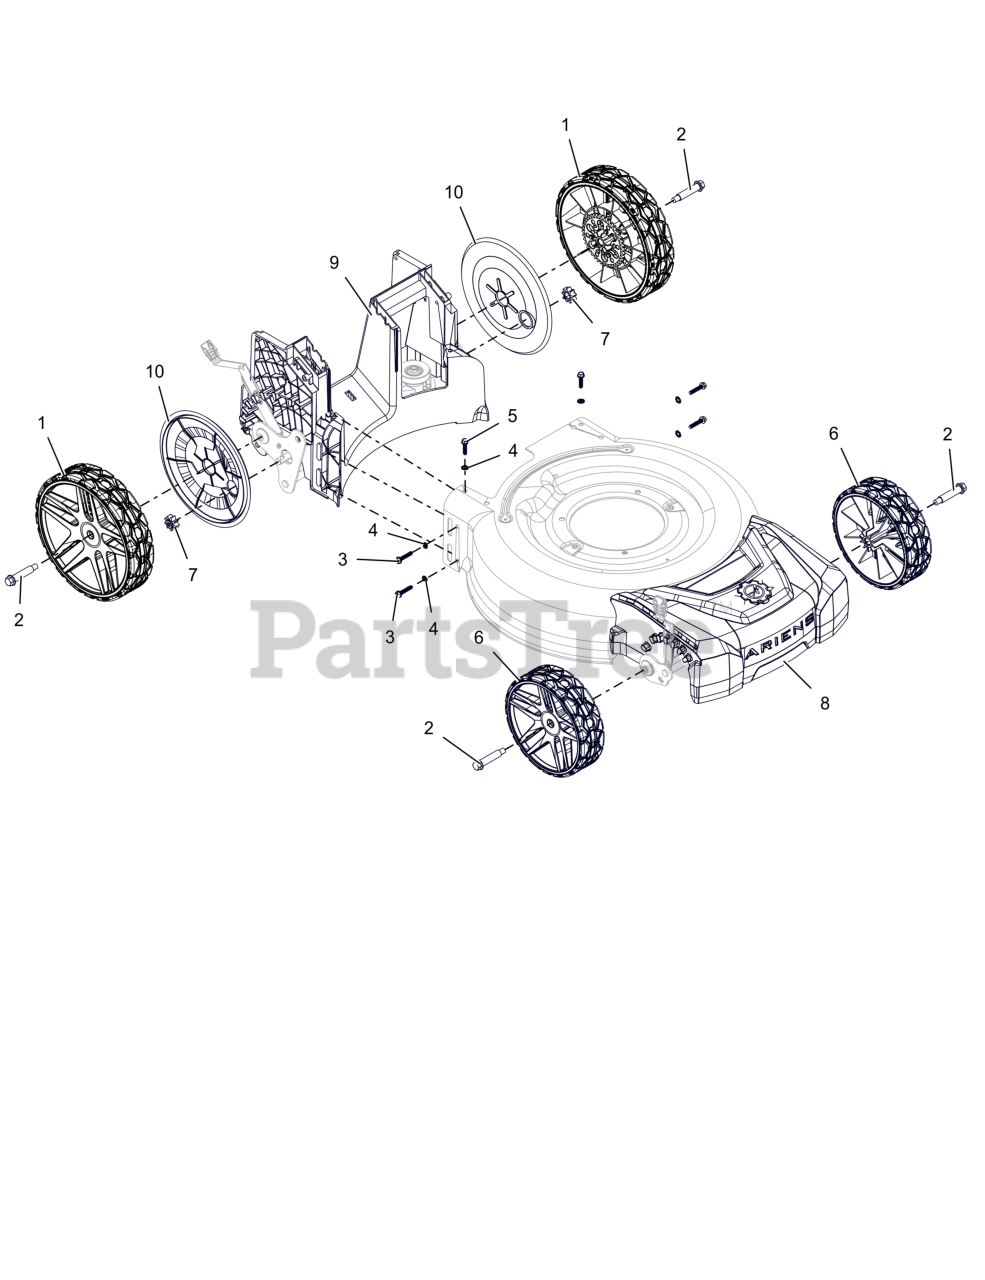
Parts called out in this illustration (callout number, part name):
1	ASM, WHEEL WITH GEAR - 10" PM
2	BLT, SHLDR HWH .325X1.981X 3/8-16
3	SCR, HI-LO HWH 1/4-15 X 1.25
4	WSHR-LK-EXT, .256X.510X.028
5	SCR, HI-LO HWH 1/4-15 X 1.00
6	WHEEL, 8" - BLACK
7	GEAR, RWD SPUR
8	COVER, FRONT
9	BAFFLE, RWD
10	COVER, DUST - 10"
